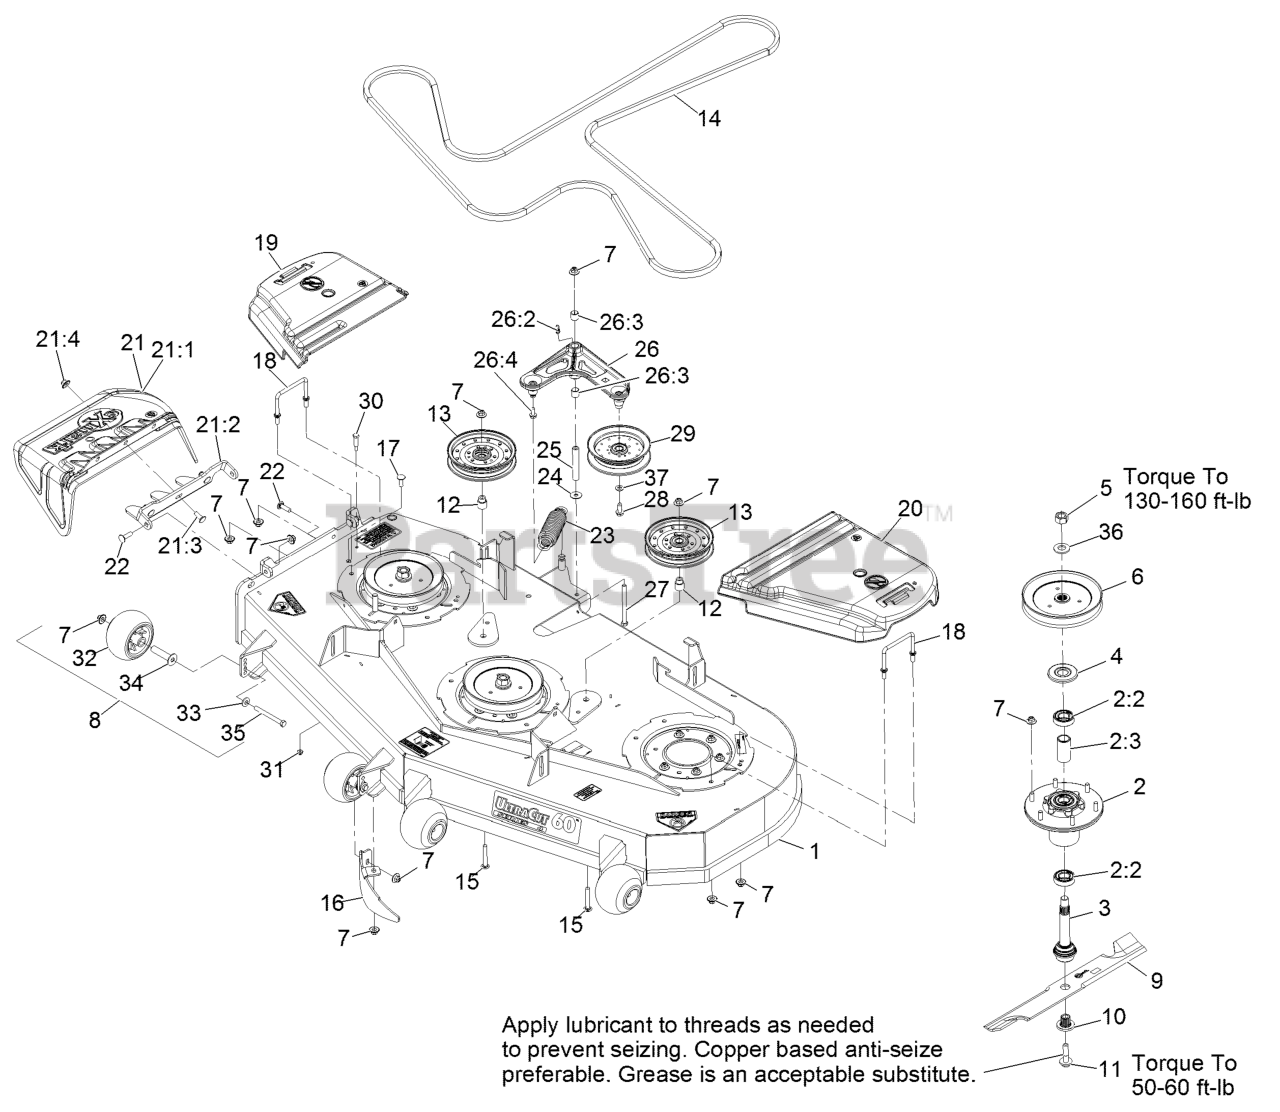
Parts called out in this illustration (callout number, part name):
1	DECK ASM,W/DECALS 604
2	ASM-CUTTER HSG WITH BEARINGS
2:2	BEARING-BALL
2:3	SPACER-BEARING
3	ASM-SPINDLE AND SEAL
4	GUARD,BEARING TOP .989
5	NUT-HEX
6	SHEAVE,BLADE DRIVE 7.25
7	Nut-Nyloc 3/8-16 Flg
8	KIT, ANTI-SCALP ROLLER
9	Blade-Extreme 2, 20.50"
10	BUSHING,SPLINED
11	SCREW,SEMS 1/2-20 X 2.19
12	BUSHING-IDLER
14	BELT-V
15	SCREW-CARR
16	DOGLEG - LZ60
17	SCREW-CARR
18	WIREFORM-COVER
19	COVER-BELT, RH
20	COVER-BELT, LH
21	ASM,DISCHARGE CHUTE
21:1	CHUTE,DISCHARGE
21:2	BRACKET,DISCHARGE CHUTE
21:3	SCREW-CARR
21:4	Nut-Nyloc 3/8-16 Flg
22	Bolt-Carriage 3/8-16 X 1 1/4
23	SPRING-EXTENSION
25	BUSHING
26	IDLER ARM ASM
26:2	FITTING-GREASE, 90 DEG
26:3	SLEEVE-BEARING
26:4	SCREW-THD ROLL, HWH
27	SCREW-HH
28	SCREW-FORMING, THREAD
30	BOLT-SHOULDER
32	ROLLER-SCALP, ANTI
33	WASHER-BELLEVILLE
34	AXLE, ROLLER
35	SCREW-HH 3/8-16 X 3 3/4 GR 8
37	WASHER-FLAT
